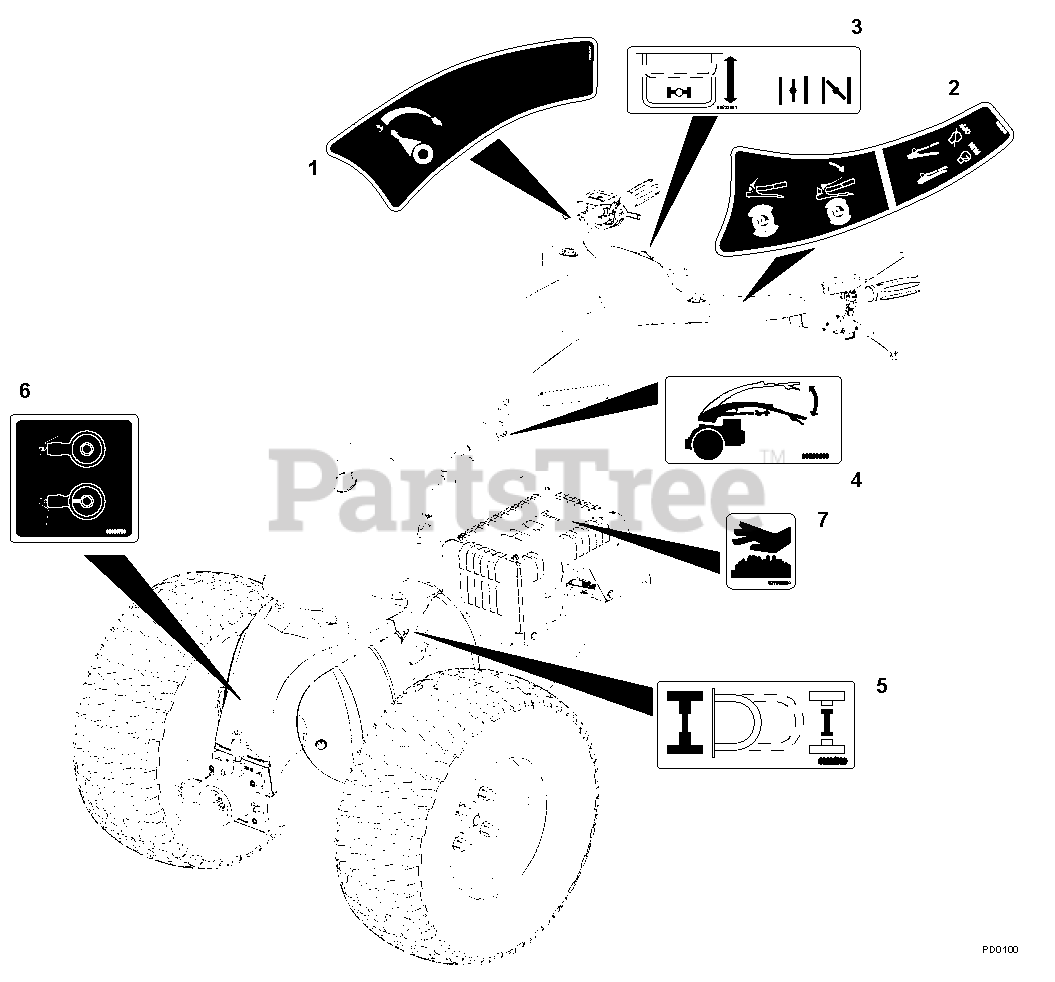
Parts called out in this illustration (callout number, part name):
1	Decal, Control Panel Right Hand
2	Decal, Park Switch/OPC Control
3	Decal, Differential Lock
4	Decal, Handle Adjustment
5	Decal, Drive Disengagement
6	Decal, Attachment Lock
7	Decal, Hot Surface
